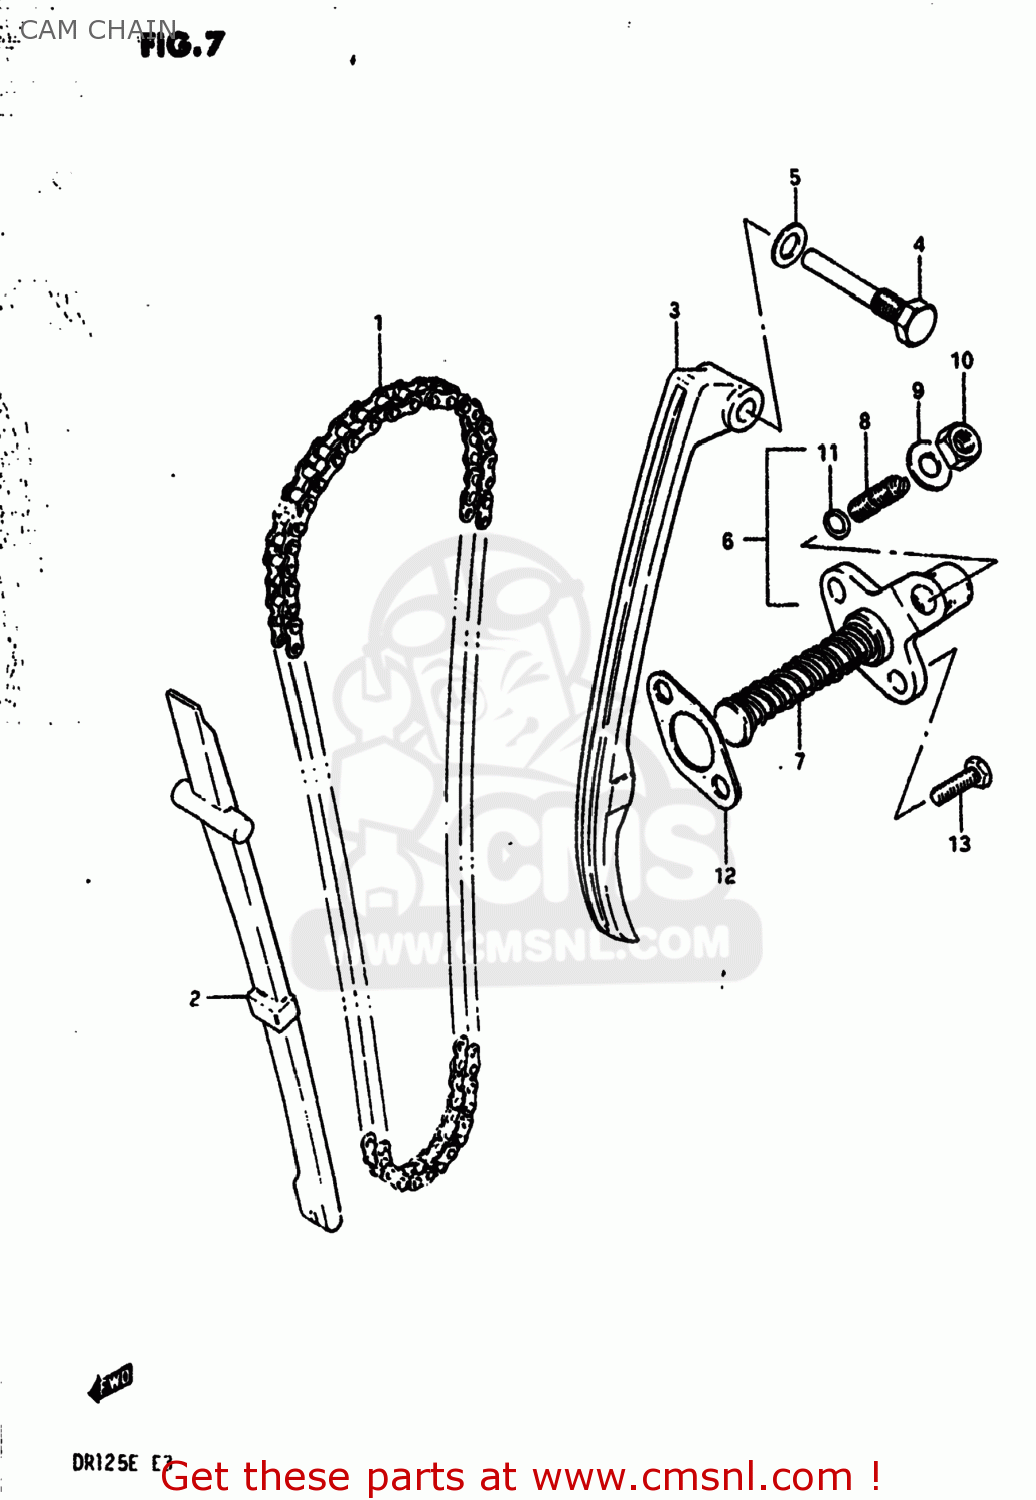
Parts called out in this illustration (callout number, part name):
1	CHAIN,CAMSHAFT DRIVE
2	GUIDE,CAM CHAIN
3	TENSIONER,CAM CHAIN
4	BOLT,CAM CHAIN TENSIONER
5	GASKET 8.2X14X1 (NAS)
6	ADJUSTER ASSEMBLY,TENSIONER
7	SPRING
8	SCREW
9	WASHER,8.5X16X
10	NUT
11	O RING(D:1.9,ID:5.7)
12	GASKET,TENSIONER ADJUSTER (NAS)
13	BOLT
